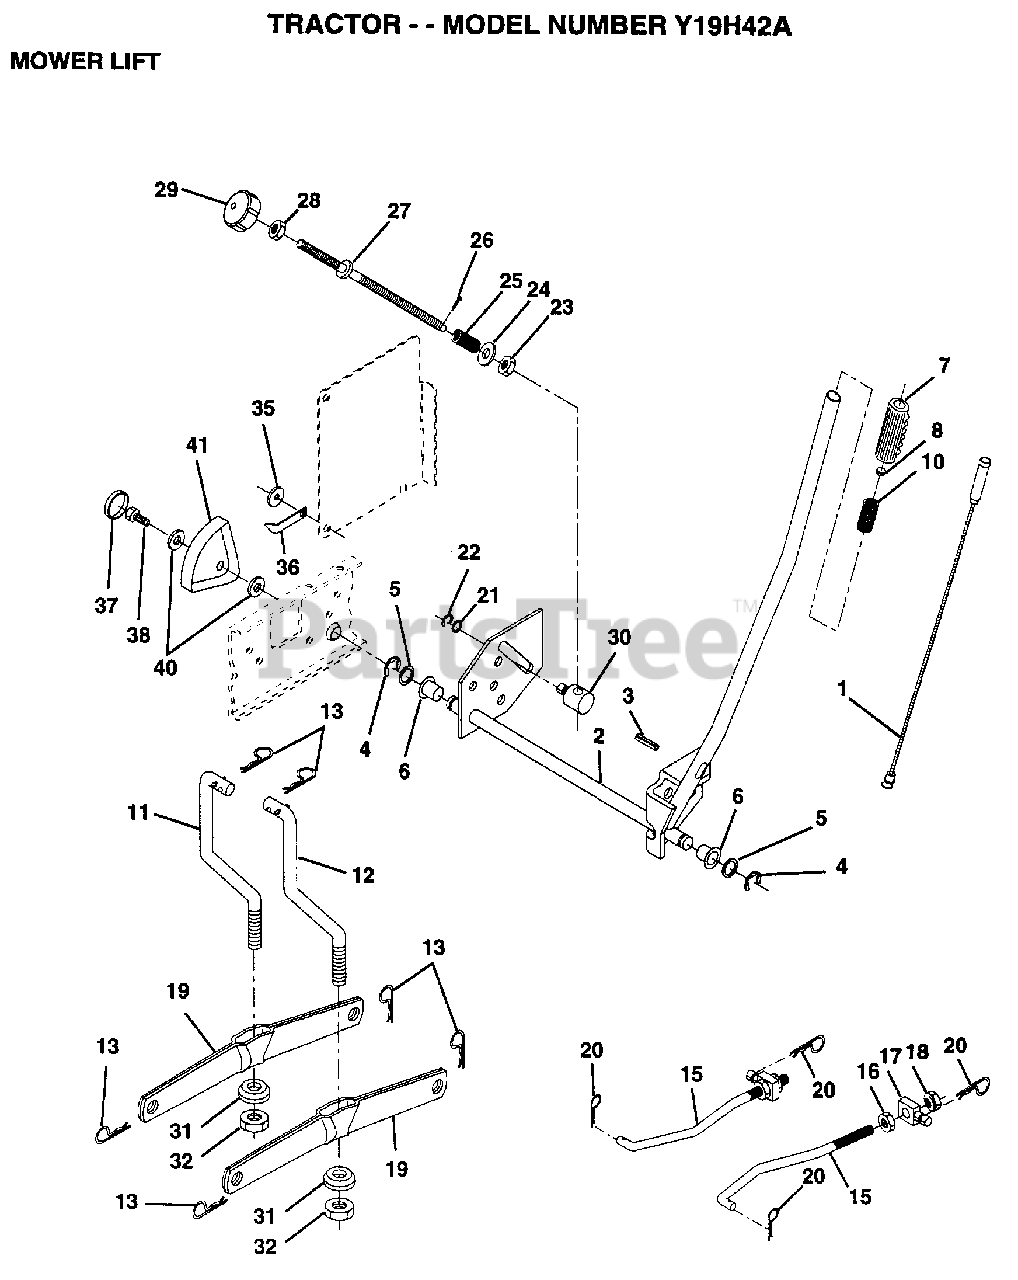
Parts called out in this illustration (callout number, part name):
1	WIRE.ASM.INNER
2	SHAFT.ASM.LIFT.RH
5	WASHER
6	NYLON BEARING
7	GRIP
8	Button Plunger Black
15	LINK.FRONT
16	NUT
17	TRUNION
18	NUT.LK.W/WSH.1/2.
19	ARM SUSP REAR
20	RETAINER.SPRING
21	WASHER 15/32 X 3/4 X 16 GAUGE
22	KLIP RING
23	No Desciption for Part
24	WASHER
25	SPRING.COMP.INF.H
27	ROD.ADJ.LIFT
28	NUT
29	KNOB INF 3/8-16
30	TRUNION LT
31	BEARING PVT LH
32	NUT.CROWNLOCK.3/8
35	WASHER T
36	POINTER HGT IND
37	PLUG,HOLE
38	SCREW
40	WASHER
41	HEIGHT INDICATOR
